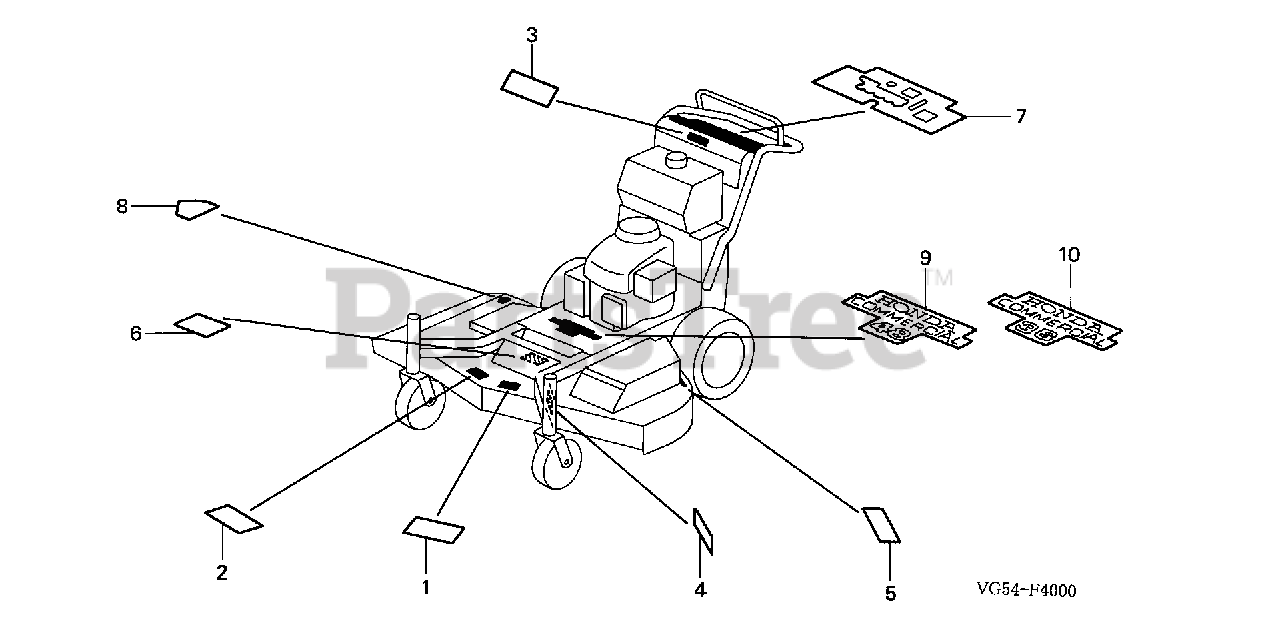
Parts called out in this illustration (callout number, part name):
1	MARK, BLADE DANGER
2	MARK, BLADE WARNING
4	MARK, FR. HEIGHT ADJUSTMENT
5	MARK, RR. HEIGHT ADJUSTMENT
6	MARK, SHIELD WARNING
8	MARK, DANGER (CPSC)
10	MARK, SALES POINT
